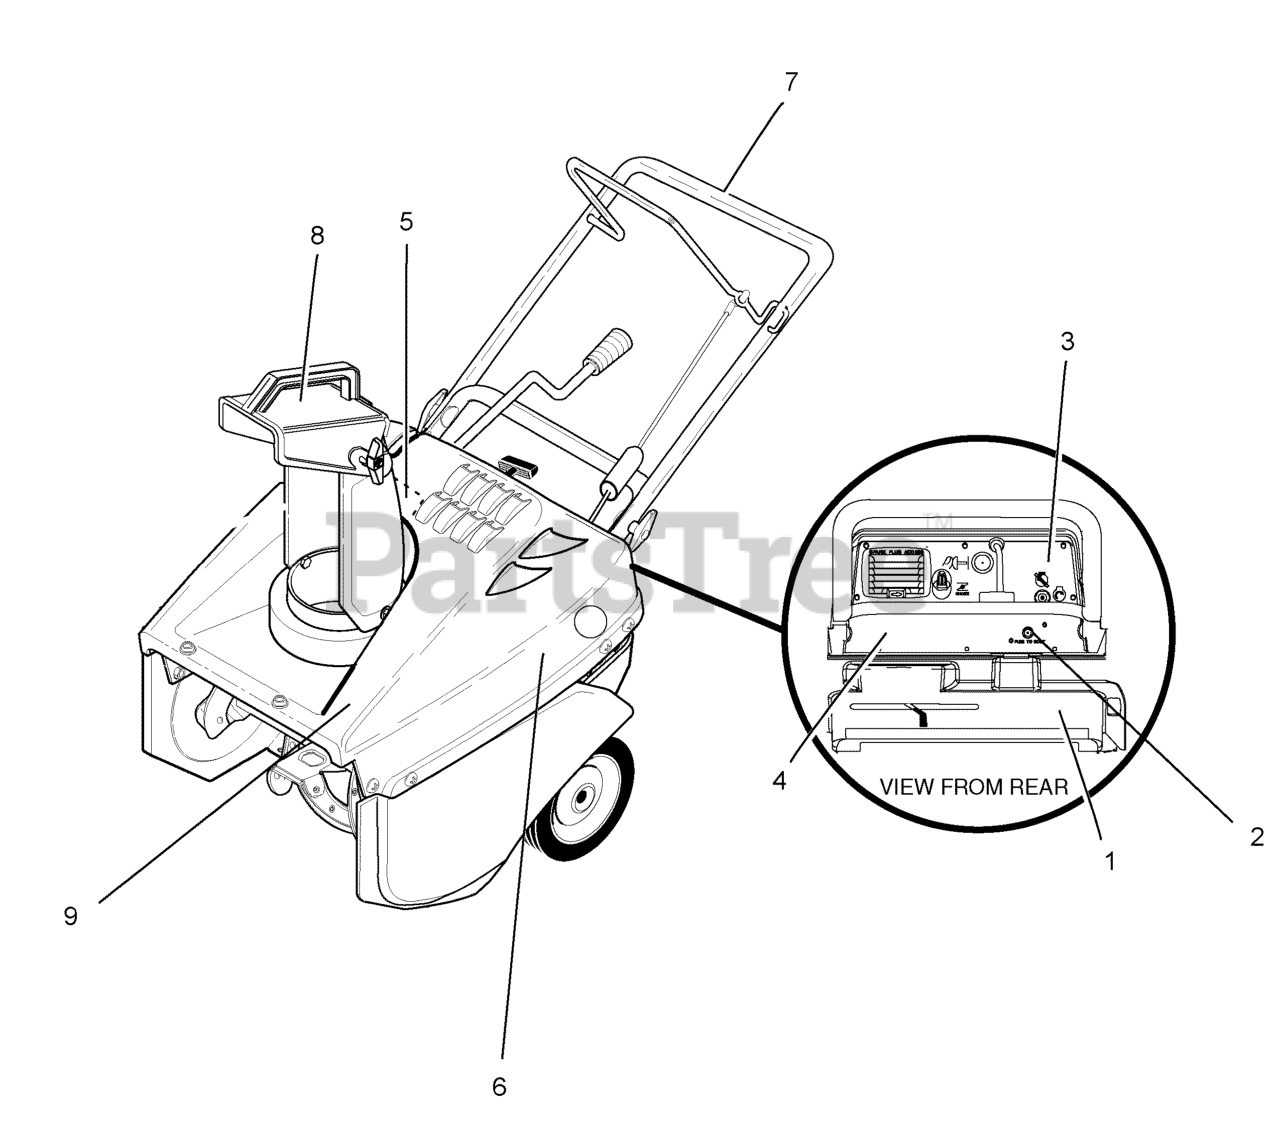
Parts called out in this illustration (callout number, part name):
1	DECAL, EPA, MASS *
2	DECAL, ELECTRIC START, COVER UP
2	DECAL, ELECTRIC START
3	DECAL, DASH PANEL
4	DECAL, HUSQVARNA
5	DECAL, HUSQVARNA 5021R
5	DECAL, HUSQVARNA 5021E
6	DECAL, WARNING HOT MUFFLER
7	DECAL, AUGER CONTROL
8	DECAL, DANGER CHUTE
9	DECAL, DANGER AUGER, FOOT
